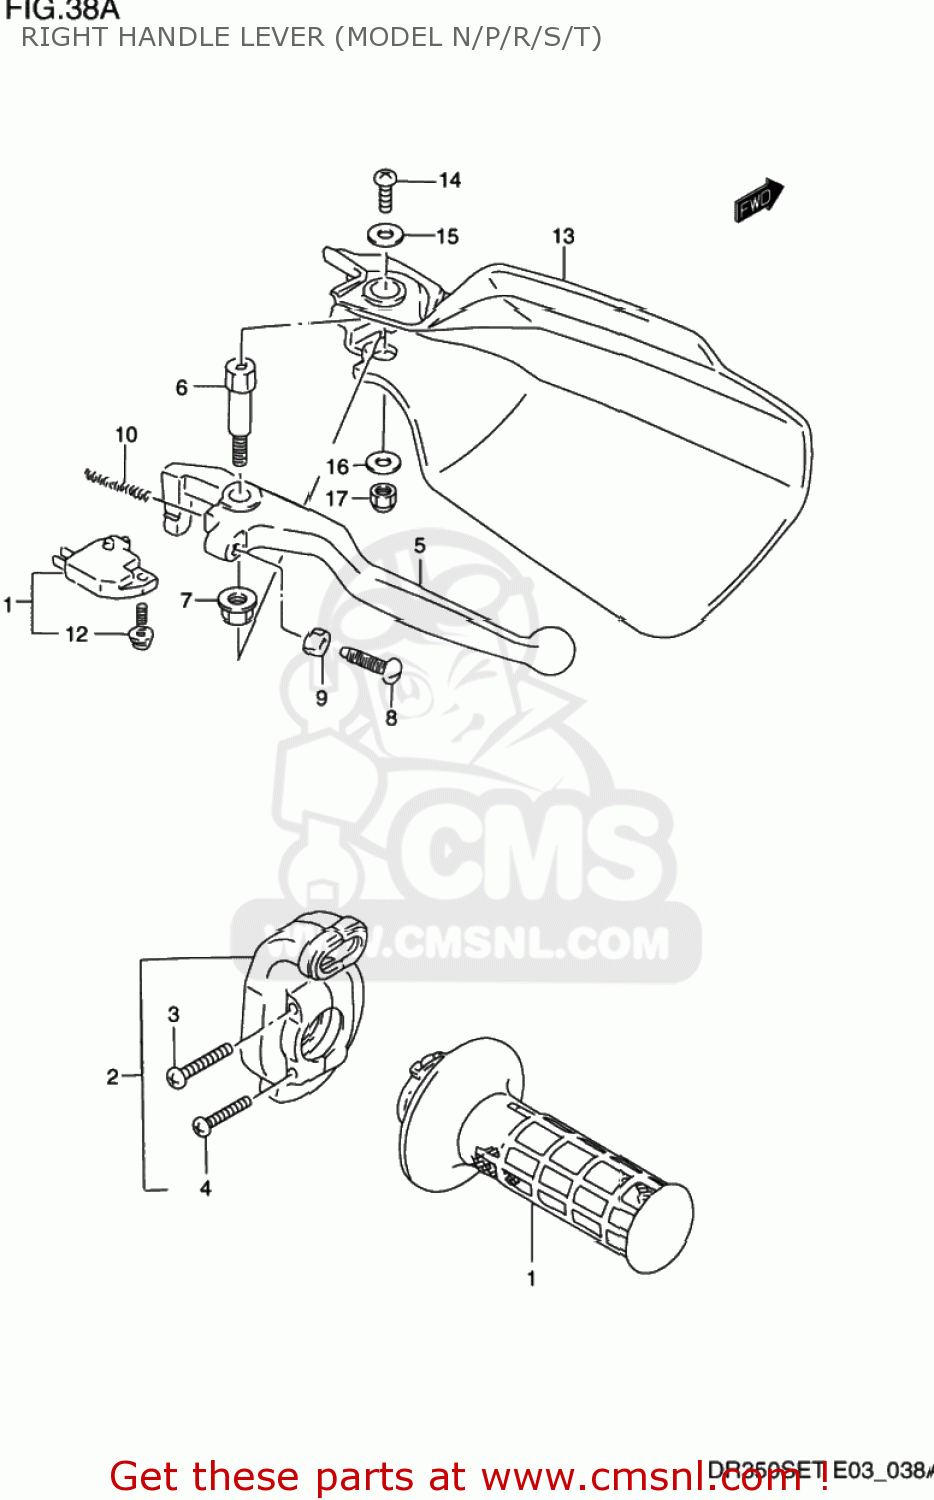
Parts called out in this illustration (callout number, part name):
1	GRIP,THROTTLE
2	CASE ASSY,THROTTLE
3	SCREW(5X25)
4	SCREW 5X20
5	LEVER,BRAKE
6	BOLT,BRAKE LEVER PIVOT
7	NUT 6MM
8	BOLT,ADJUST
9	NUT ,5MM
10	SPRING,RETURN
11	SWITCH ASSEMBLY,STOP
12	SCREW
13	COVER,KNUCKLE,R
14	SCREW
15	WASHER (5.5X16X1.2)
16	WASHER (6.5X17X1.6)
17	NUT 6MM
